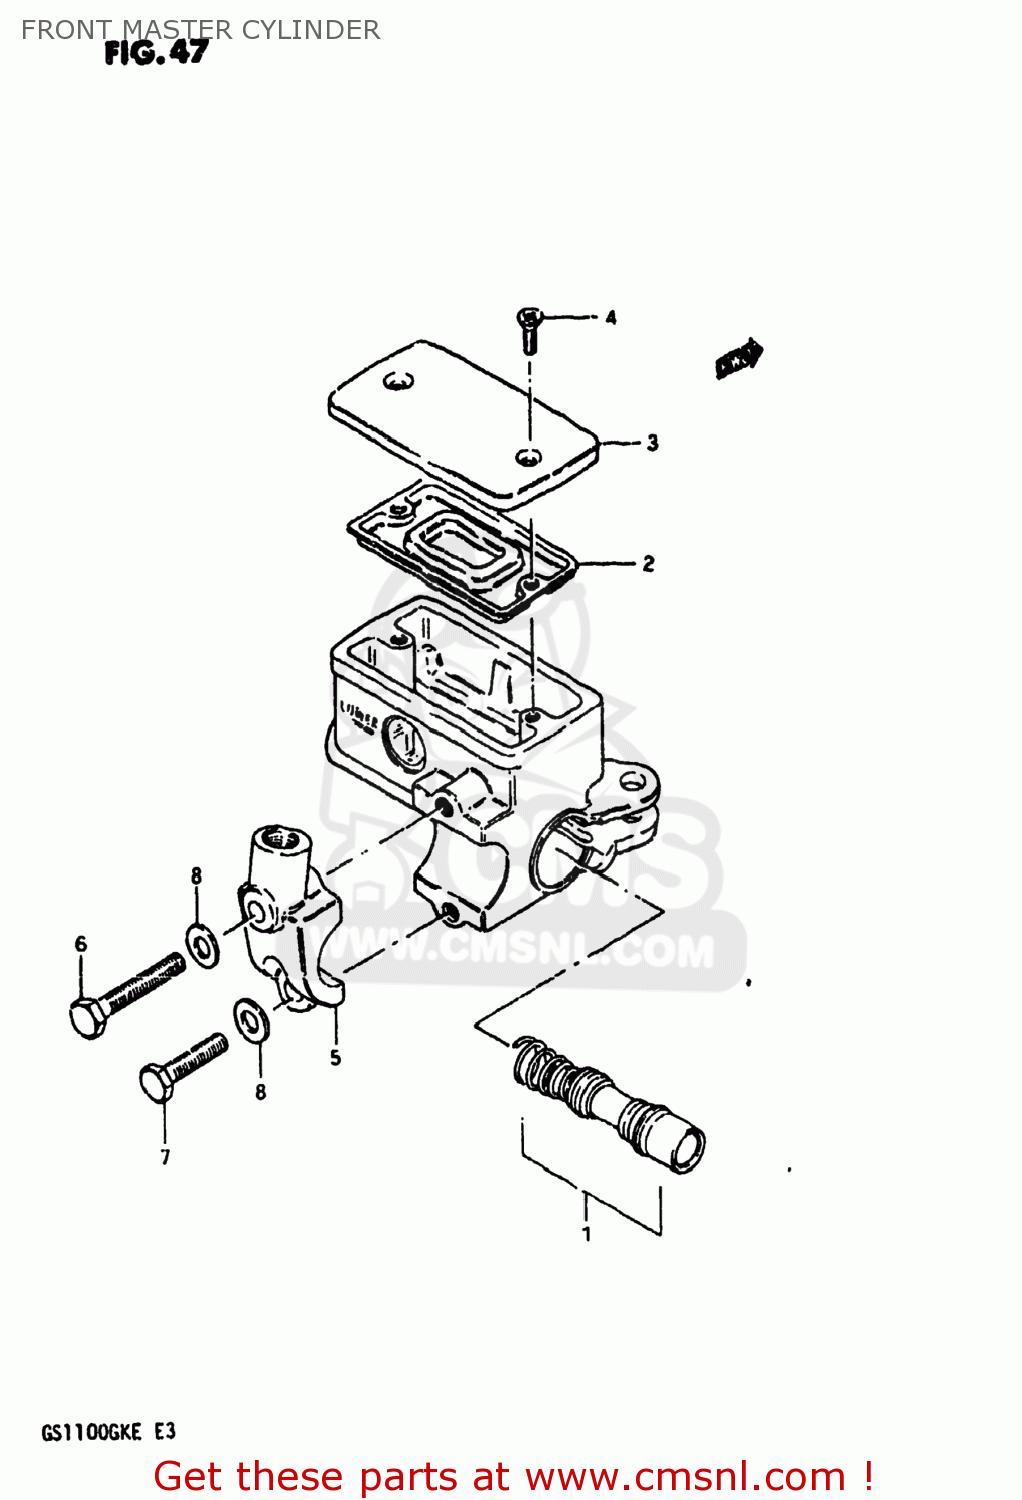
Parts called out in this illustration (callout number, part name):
1	PISTON & CUP SET
2	3
3	CAP
4	SCREW
5	HOLDER
6	BOLT 6X40
7	BOLT
8	WASHER
